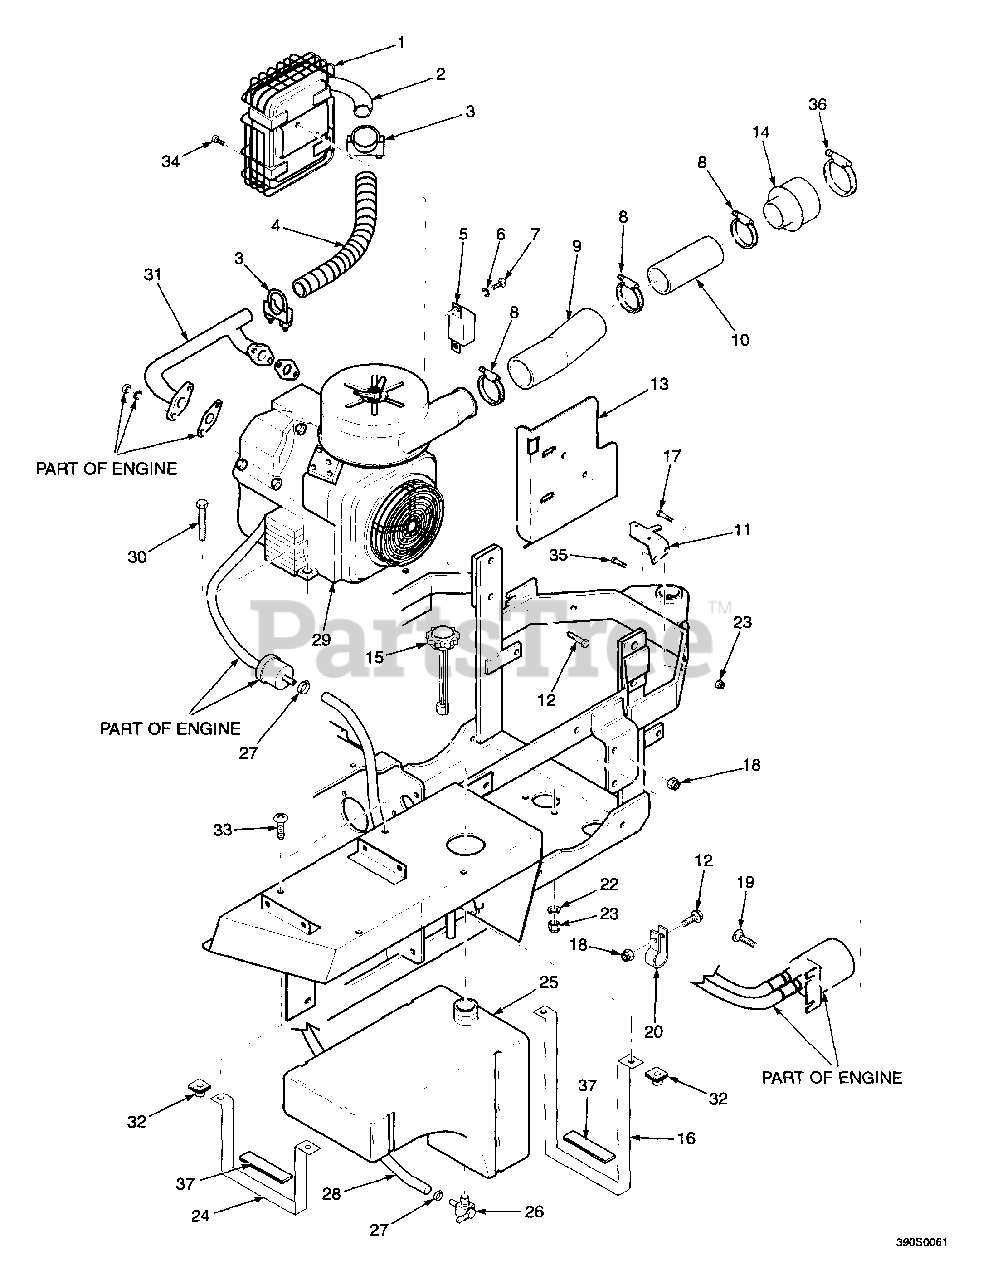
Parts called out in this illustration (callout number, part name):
1	Guard, Muffler
2	Muffler
3	Clamp, Muffler
4	Exhaust Pipe, Flexible
5	Relay
6	Lockwasher, 1/4
7	Machine Screw, Round Head, 1/4-20 x 1/2"
8	Clamp, 2.25 Dia
9	Hose, Air Intake
10	Pipe Ext, Air Cleaner
11	Mounting Brkt., Air Cleaner
12	Serr. Flange Hex Head, CPSCR, 5/16-18 X 3/4"
13	Guard, Muffler
14	Precleaner, Air Intake
15	Gap, Fuel Tank, with Gauge
16	Strap, Fuel Tank - Rear
17	Hex Head Bolt, 3/8-16 x 1.50"
18	Hex Locknut, Elastic Stop, 5/16-18
19	Carriage Bolt, 5/16-18 x 1.00"
22	Lockwasher, 3/8"
23	Hex Locknut, Elastic Stop, 3/8-16
24	Strap, Fuel Tank-Front
25	Fuel Tank
26	Valve, Fuel Shut Off
27	Clamp, Hose
28	Fuel Hose - 20" Long
29	Engine, Kohler - 20 HP (20CH)
29	Engine, Kohler - 22 HP (22CH)
30	Bolt, Hex Head, 3/8-16 x 1-3/4
31	Manifold, Exhaust
33	Machine Screw, Round Head, 1/4-20 x 2.00"
34	Capscrew, Socket Head, #10-32 x 1/2"
35	Hex Head Bolt, 3/8-16 x 1.25"
36	Clamp, Hose 5.50"
37	Rubber Pad
